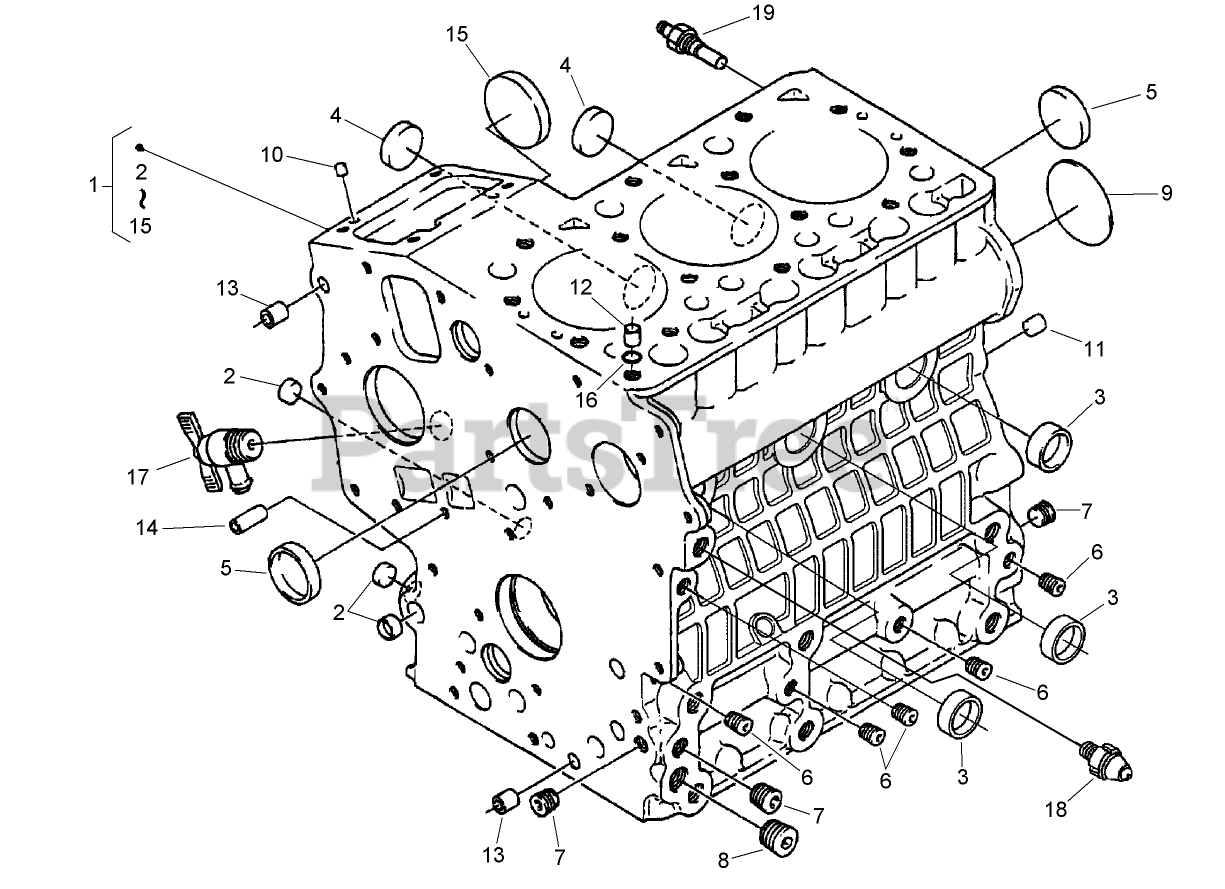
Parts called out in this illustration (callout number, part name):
1	CRANKCASE
2	CAP-SEALING
3	CAP-SEALING
4	CAP-SEALING
5	CAP-SEALING
6	PLUG
9	PLUG-EXPANSION
10	PIN-STRAIGHT
11	PIN-STRAIGHT
12	PIN-PIPE
13	PIN-PIPE
14	PIN-PIPE
15	COVER-FUEL, CAMSHAFT
16	O-RING
17	DRAIN COCK ASM
18	SWITCH-OIL
19	THERMOSWITCH
